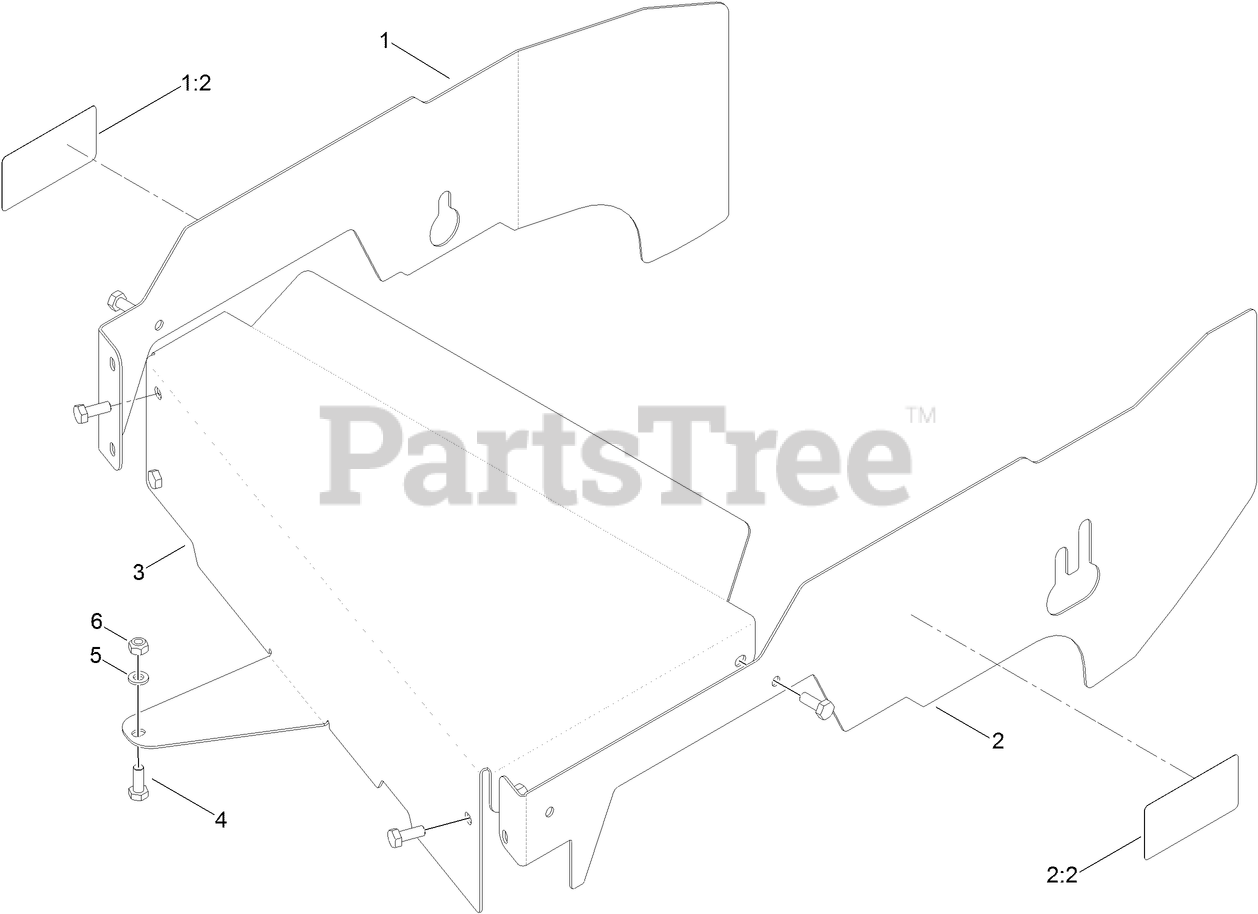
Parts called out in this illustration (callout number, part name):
1	GUARD-BELT, DECK (RH)
1:2	DECAL-WARNING
2	GUARD-BELT, DECK (LH)
2:2	DECAL-WARNING
3	GUARD-BELT, DECK
4	SCREW-HH
5	NUT-LOCK
6	WASHER-FLAT
